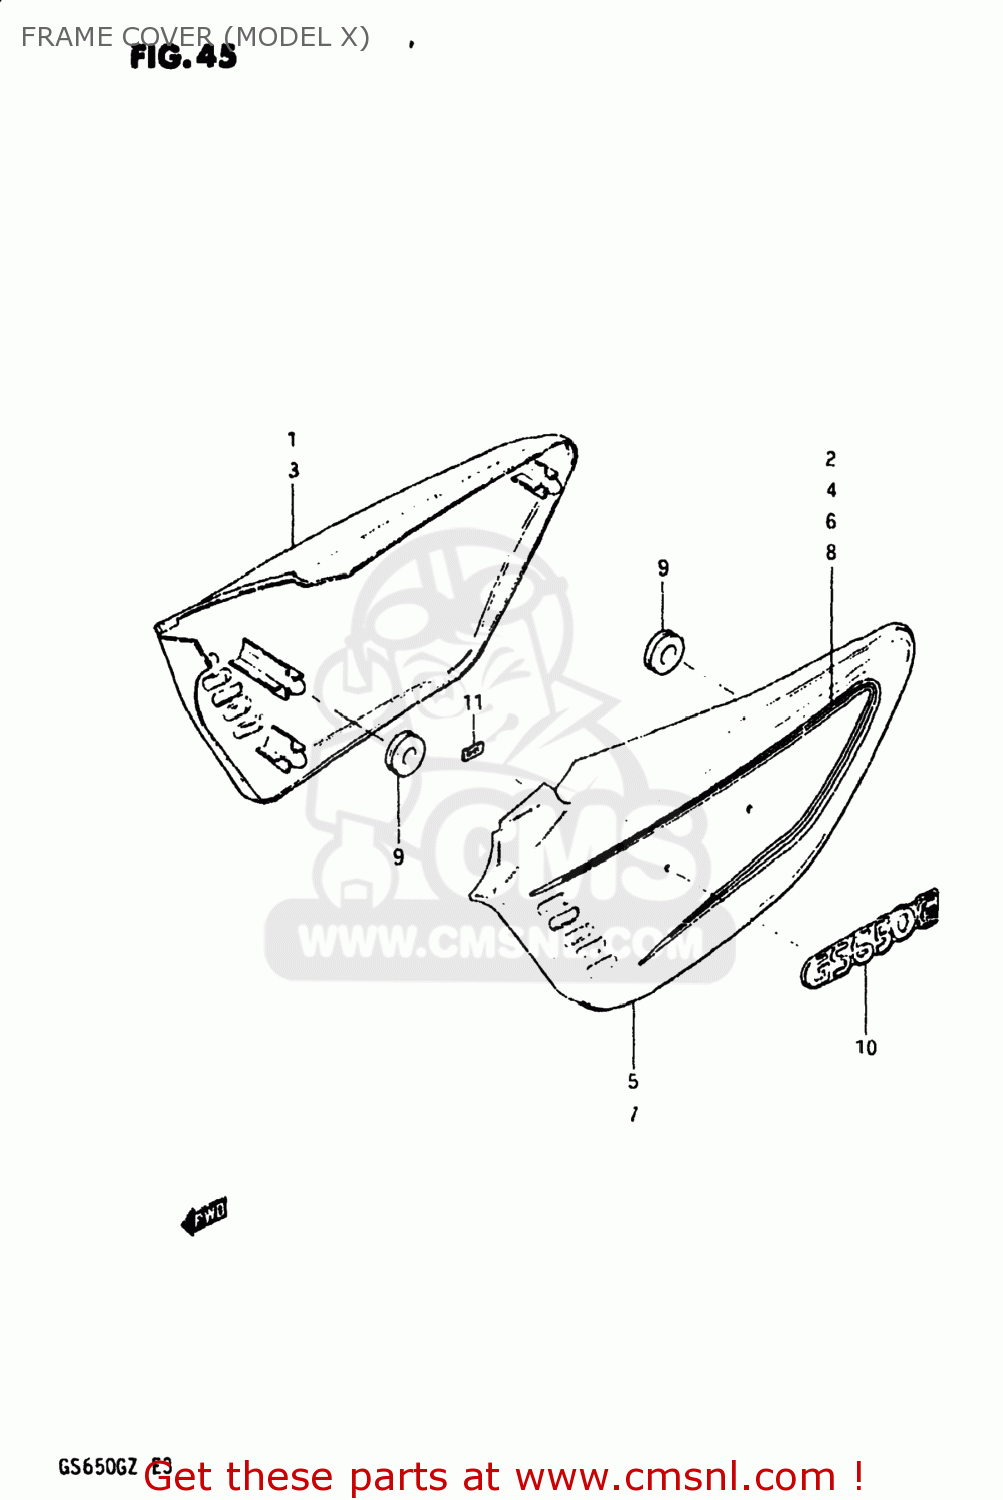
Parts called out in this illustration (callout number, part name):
1	COVER,FRAME,RIGHT
2	TAPE, RH
3	COVER,FRAME,RIGHT
4	TAPE,FRAME COVER
5	COVER,FRAME,LEFT
6	TAPE,FRAME COVER
7	COVER,FRAME,LEFT
8	TAPE,FRAME COVER
9	CUSHION
10	EMBLEM,FRAME COVER
11	NUT
